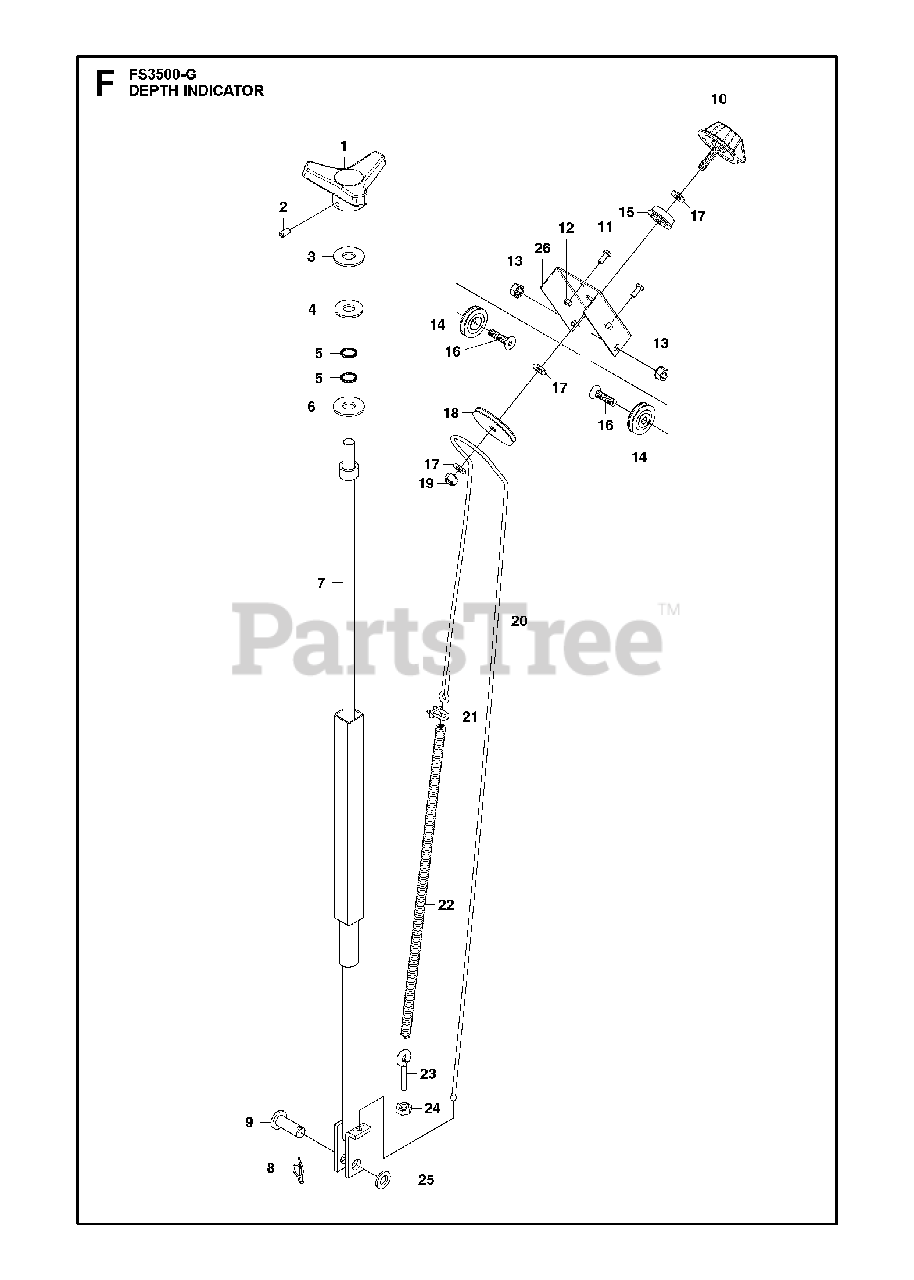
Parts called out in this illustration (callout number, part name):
11	SCREW CRPANM
12	HEXAGON LOCKING NUTIncluded in Tank, pos 5
17	WASHER
19	NUT
25	WASHER
